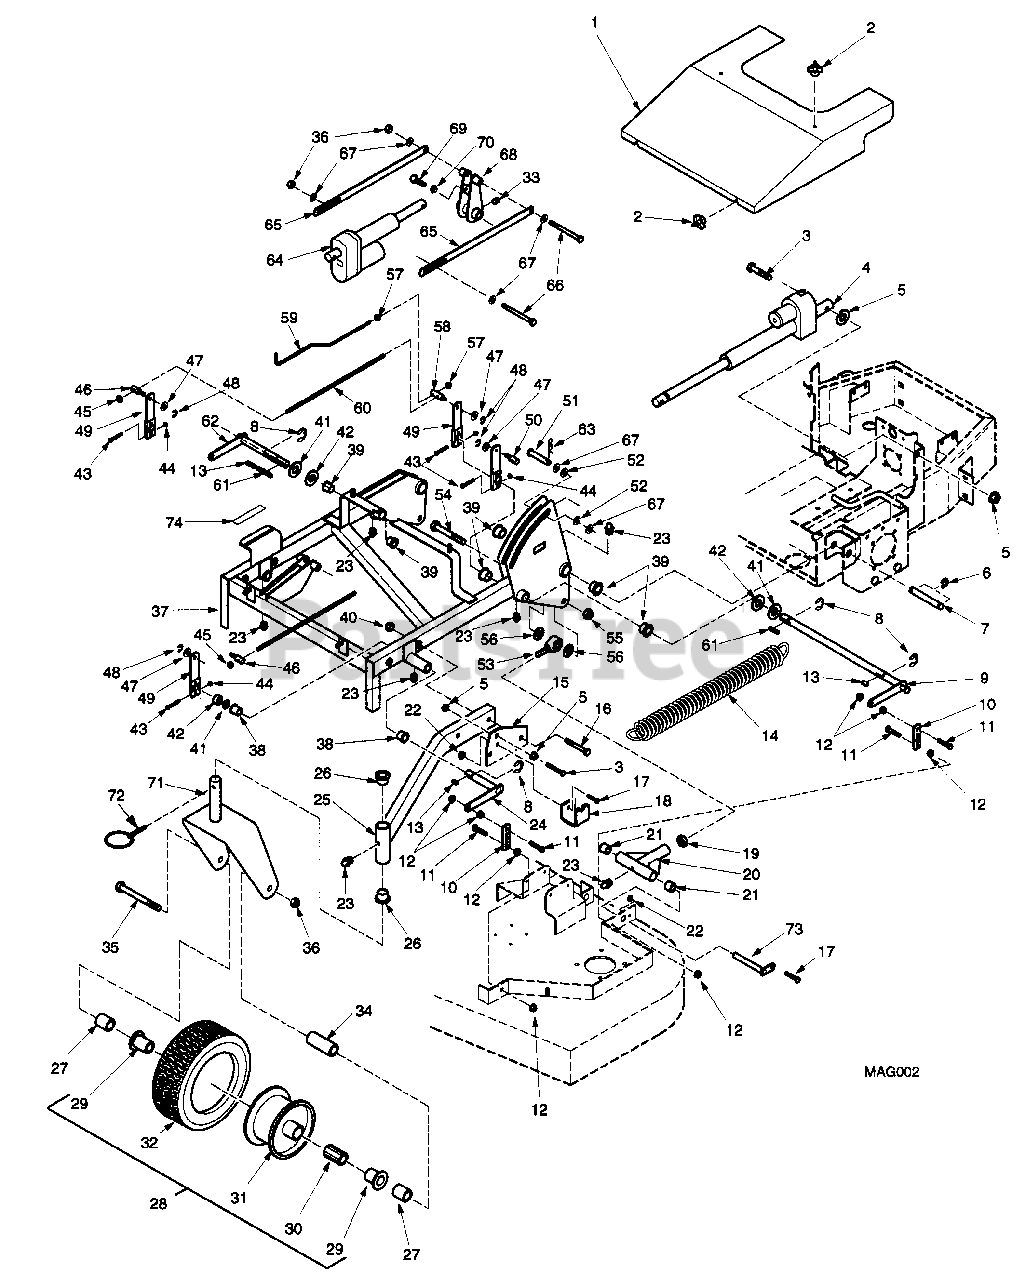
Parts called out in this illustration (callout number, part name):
1	COVER, BELT
2	WINGNUT, PLASTIC, 3/8-16
3	BOLT, HEX HEAD, 1/2-13 X 2-1/2
4	ACTUATOR, DECK LIFT
5	SERR. FL. HEX NUT, 1/2-13
6	RETAINING RING, 1.125 EXT
7	PIN, DECK SUPPORT MOUNTING
8	RETAINING RING, 1.00 EXT "E"
9	LIFT BELLCRANK, LH REAR
10	LINK, DECK SUPPORT
11	BOLT, HEX HEAD, 7/16-14 X 1-3/4
12	SERR. FL. HEX NUT, 7/16-14
13	KEY, 1/4 X 1/4 X 3/4
14	SPRING, DECK LIFT
15	ANCHOR, DECK SPRING
16	BOLT, HEX HEAD, 5/8-11 X 5-1/2
17	SERR. FL. HEX HEAD CPSCR, 5/16-18 X 3/4
18	RETAINER, SPRING
19	HEX NUT, 3/4-16
20	PUSH ROD ASSY(INCLUDES 19, 21, 23, 53)
21	BUSHING, OLITE - 3/4 ID
22	SERR. FL. HEX NUT, 5/16-18
23	GREASE FITTING
24	LIFT BELLCRANK, FRONT
25	TUBE, LH CASTER(SHOWN)
26	BUSHING, OLITE - 1.00 ID
27	SPACER
28	WHEEL ASSEMBLY, CASTER(INCLUDES 29,30,31,32)
29	RETAINER
30	BEARING, ROLLER
31	RIM
32	TIRE
33	SETSCREW, HEX SOCKET, 5/16-18 X .75
34	SLEEVE, CASTER WHEEL
35	BOLT, HEX HEAD, 1/2-13 X 6-1/2
36	HEX LOCKNUT, ELASTIC STOP, 1/2-13
37	FRAME, DECK SUPPORT(INCLUDES 23,38,39,74)
38	BUSHING, OLITE - 1-1/8 ID
39	BUSHING OLITE - 1.00 ID
40	HEX LOCKNUT, ELASTIC STOP, 5/8-11
41	FLATWASHER, 1"(1.062 X 1.75 X .10)
41	FLATWASHER, 1"(1.062 X 1.50 X .048)
42	SPACER
43	BOLT, HEX HEAD, 3/8-16 X 2
44	HEX LOCKNUT, ELASTIC STOP, 3/8-16
45	HEX NUT, 5/8-11
46	SWIVEL JOINT, RH
47	FLATWASHER, 5/8(.656 X 1.312 X .095)
48	RETAINING RING, 5/8 EXT "E"
49	LEVER, DECK LIFT
50	SWIVEL JOINT, LH
51	PIN, CLEVIS, 1/2 X 2.25
52	FLATWASHER, NYLON, 1"(.54 X 1.125 X 25)
53	ROD END, MALE, 3/4-16 RH
54	BOLT, HEX HEAD, 3/4-16 X 3
55	HEX LOCKNUT, ELASTIC STOP, 3/4-16
56	SPACER
57	HEX NUT, 3/8-16
58	SWIVEL JOINT, LH
59	ROD, HEIGHT INDICATOR
60	STUD, MOWER LIFT
61	KEY, 1/4 X 1/4 X 1-1/4
62	LIFT, BELLCRANK, RH REAR
63	COTTER PIN, HAIR - 0.94 X 1.62
64	ACTUATOR, CUTTING HEIGHT
65	LINK, DECK TRAVEL LIMIT
66	BOLT, HEX HEAD, 1/2-13 X 4-3/4
67	FLATWASHER, 1/2(.531 X 1.06 X .095)
68	LEVER, BELLCRANK ACTUATION
69	BOLT, HEX HEAD, 1/2-13 X 2
70	HEX NUT, 1/2-13
71	YOKE, CASTER WHEEL
72	QUICK PIN
73	SHAFT, PUSH ROD
74	DECAL, CUTTING HEIGHT
